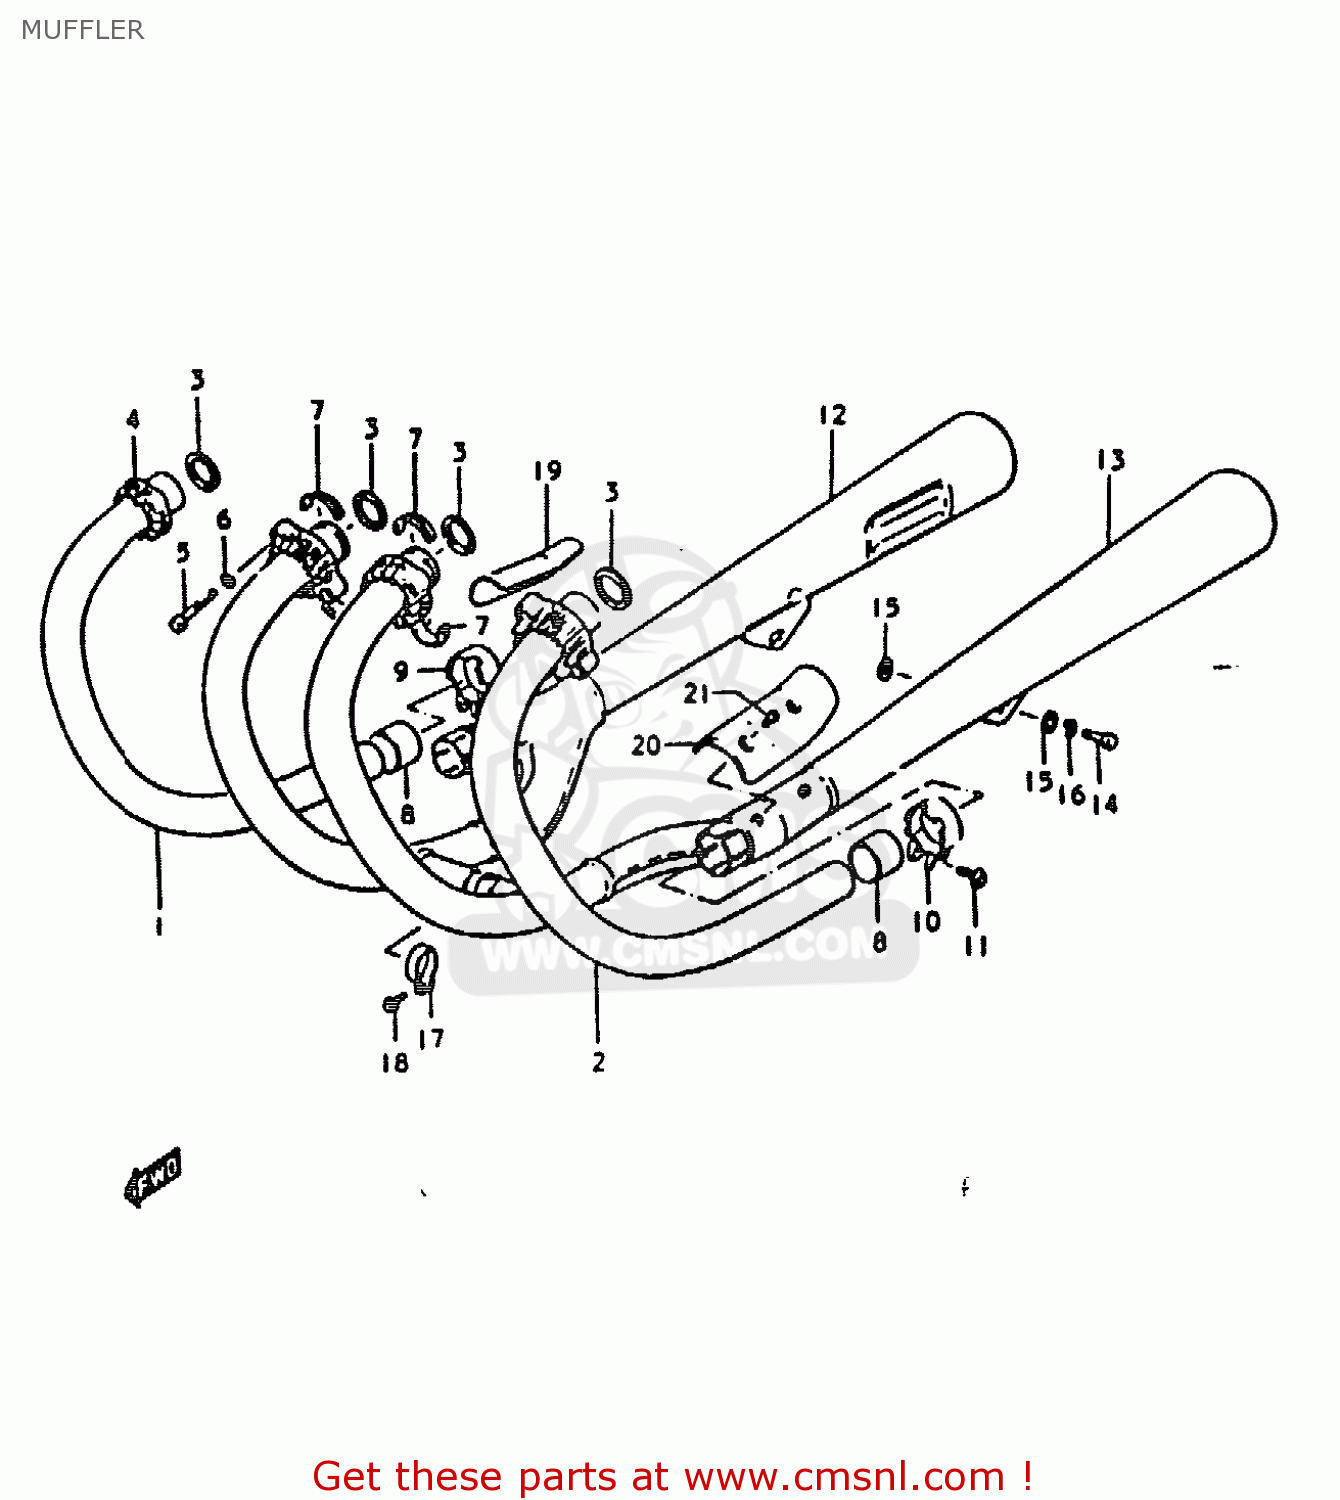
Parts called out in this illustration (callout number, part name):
1	PIPE,EXHAUST,R
2	PIPE,EXHAUST,L
3	GASKET,EXHAUST PIPE (NAS)
4	CLAMP,EXHAUST PIPE
5	BOLT
6	LOCK WASHER
7	PLATE,EXHAUST P
8	CONNECTOR,MUFFLER
9	CLAMP,MUFFLER CONNECTOR,R
10	CLAMP,MUFFLER CONNECTOR,L
11	BOLT
12	BODY,MUFFLER
13	BODY,MUFFLER
14	BOLT 10X30
15	WASHER
16	LOCK WASHER
17	CLAMP
18	BOLT
19	COVER,MUFFLER
20	COVER,MUFFLER,LEFT
21	SCREW
